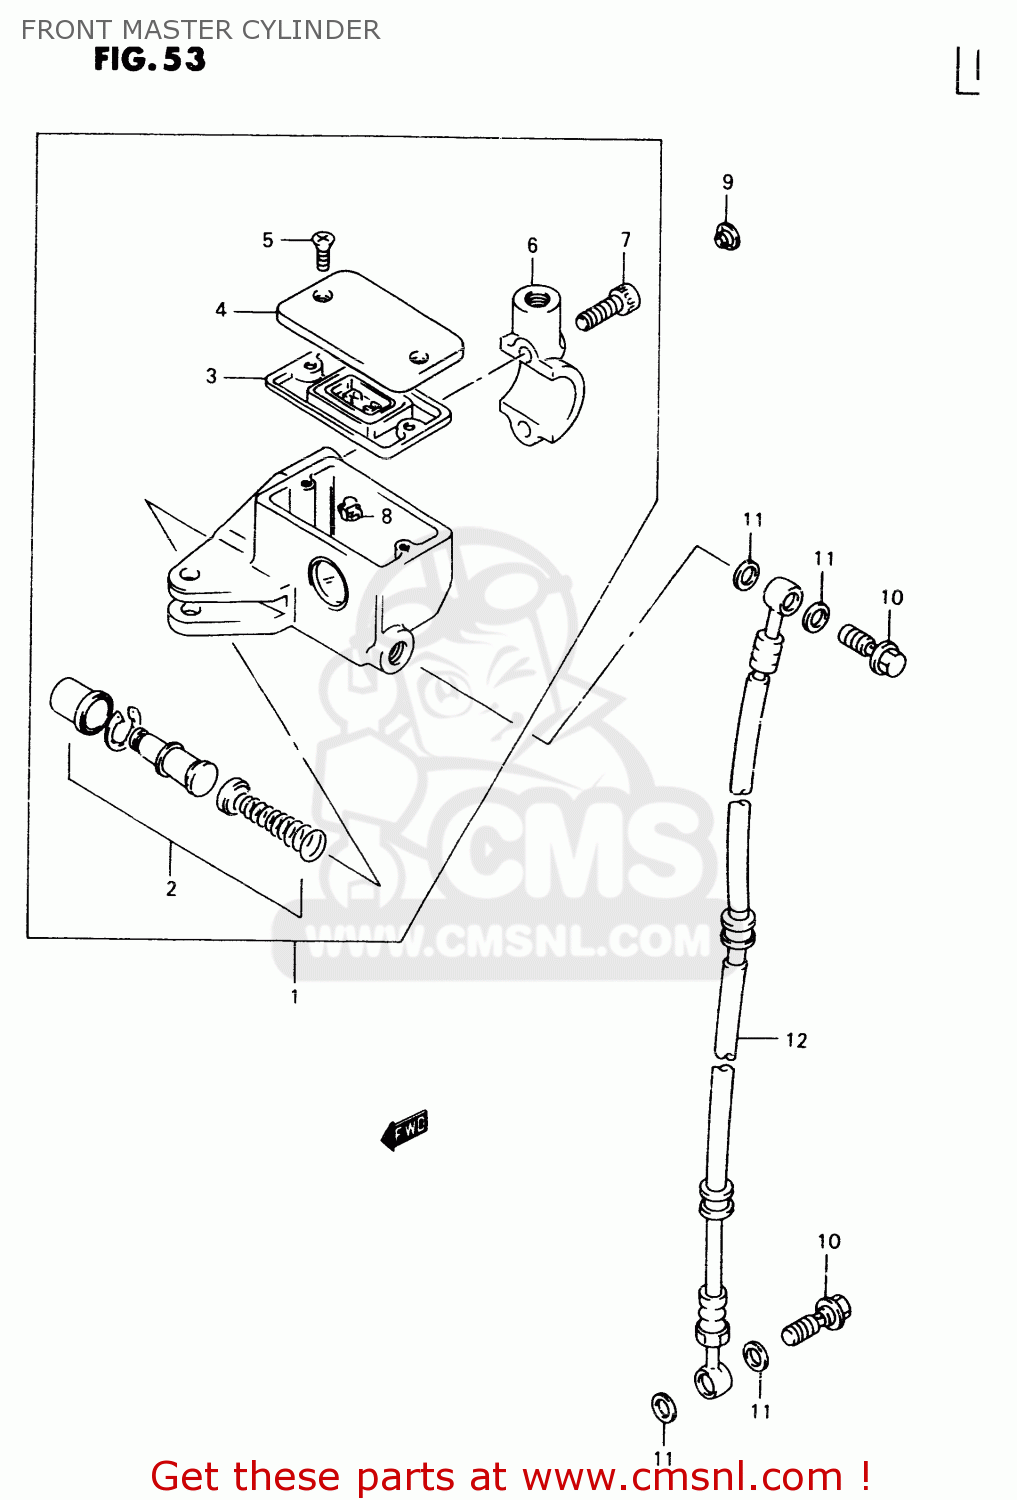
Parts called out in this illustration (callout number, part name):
1	CYLINDER ASSY,FR MASTER
2	PISTON/CUP SET
3	4
4	CAP
5	SCREW
6	HOLDER
7	BOLT
8	PROTECTOR
9	CAP(OD:10)
10	BOLT UNION
11	WASHER(10X15X1.5)
12	HOSE COMP,FRONT BRAKE
